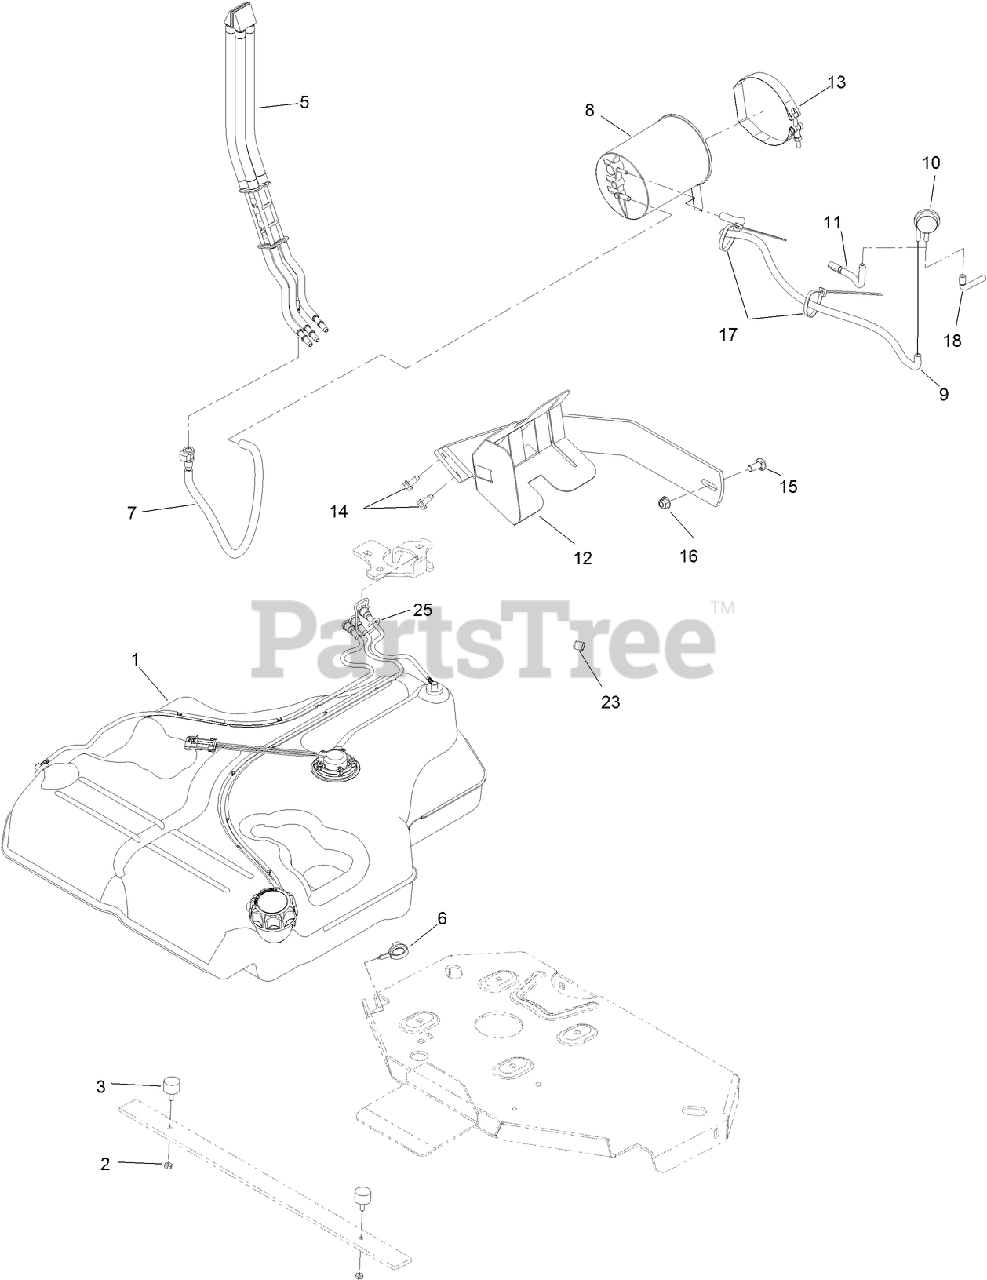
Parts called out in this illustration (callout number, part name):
1	FUEL TANK ASM
2	NUT-JAM
3	BUMPER-RUBBER (W/ STUD)
5	FUEL MANIFOLD VENT ASM
6	CLAMP-HOSE
7	VENT HOSE ASM
8	CANISTER-CARBON, 1200CC
9	HOSE-VENT, FORMED
10	VALVE-CONTROL, VACUUM
11	HOSE-VENT, FORMED
12	MOUNT-CANISTER
13	CLAMP-T-BOLT
14	SCREW-HWHTF
15	SCREW-CARR
16	NUT-HF, NI
17	TIE-PLASTIC
18	HOSE-VENT, FORMED
23	PLUG-PORT
25	RETAINER-LINE, VAPOR
